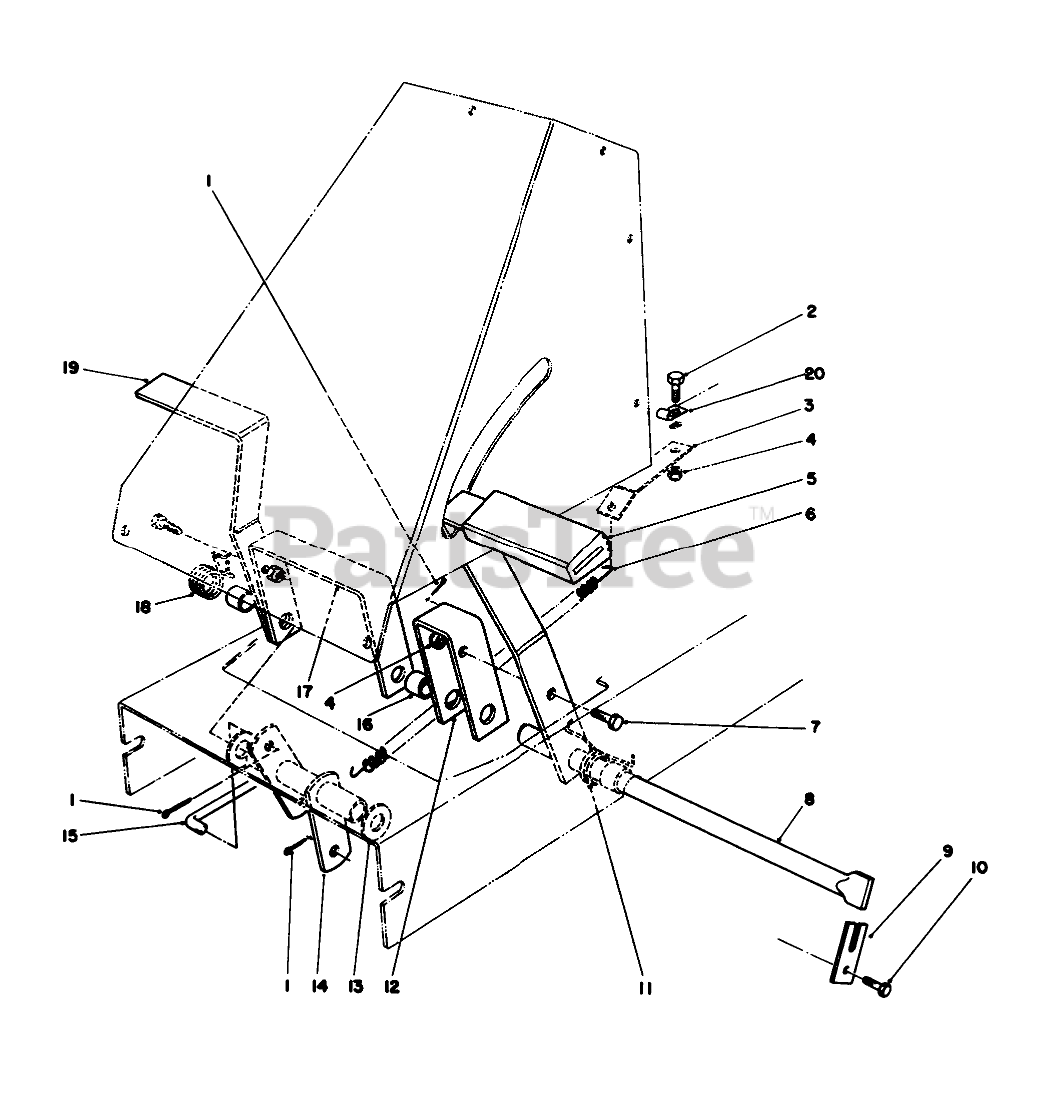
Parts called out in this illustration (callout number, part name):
1	PIN-COTTER
2	SCREW-HH
2	Screw
3	BRKT-SPRING RET
4	NUT-LOCK, NI
5	PAD-PEDAL
6	SPRING-EXTENSION
7	SCREW-HH
8	Shaft-Pedal Pivot
9	RETAINER-SHAFT
10	SCREW-HH
11	SPRING-TORS CLUTCH
12	Bracket-Clutch Pedal
13	WASHER-FLAT
14	Pivot Tube
15	ROD-ENGAGE
16	SPACER-PEDAL
17	Bracket-Brake Pedal
18	SPRING-TORS BRAKE
19	Pedal
20	CLAMP
